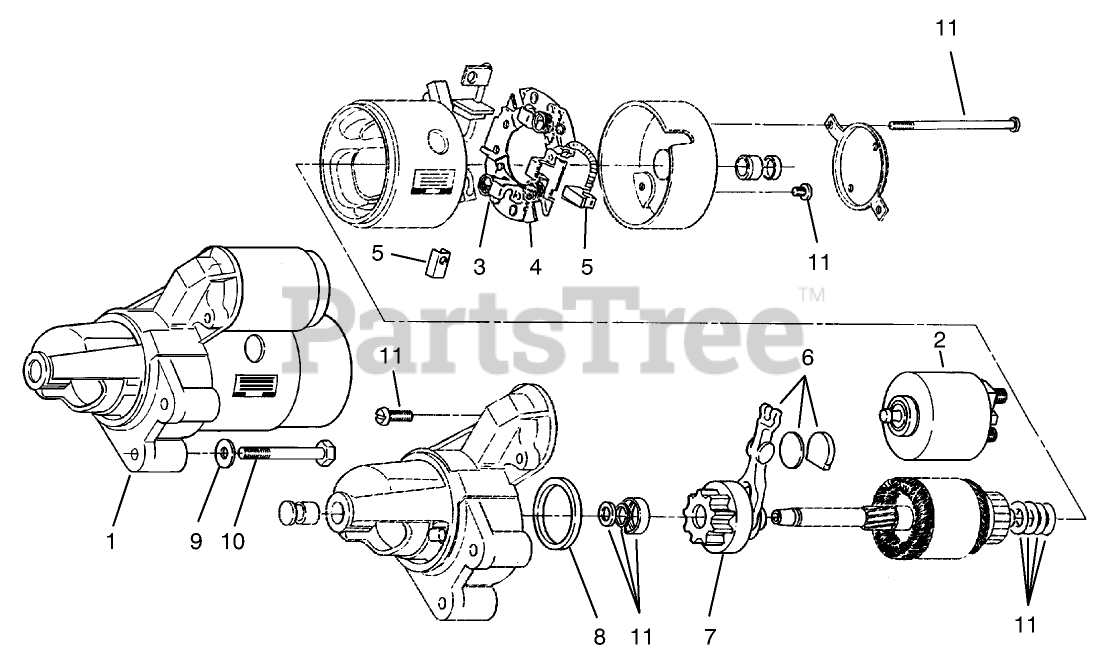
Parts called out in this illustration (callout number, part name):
1	Starter Assy
2	Kit-Starter Solenoid (Incl. Spring Plunger)
3	SPRING-BRUSH
4	Holder-Brush (Incl. Negative Brush)
5	Kit-Brush (Incl. Positive Brush (2) & Negative Brush w/Pigtail)
6	Kit-Starter Shift Lever (Incl. Wear Plate & Plug)
7	Clutch-Starter (Incl. Pinion Gear w/Clutch)
8	Dust Seal
9	WASHER
10	Bolt
11	Kit-Hardware (Incl. Solenoid Screws (2) Brush Holder Screws (2) Thru Bolts (2) Armature Shims (2) Pinion Stop Collar & Pinion Retaining Ring)
